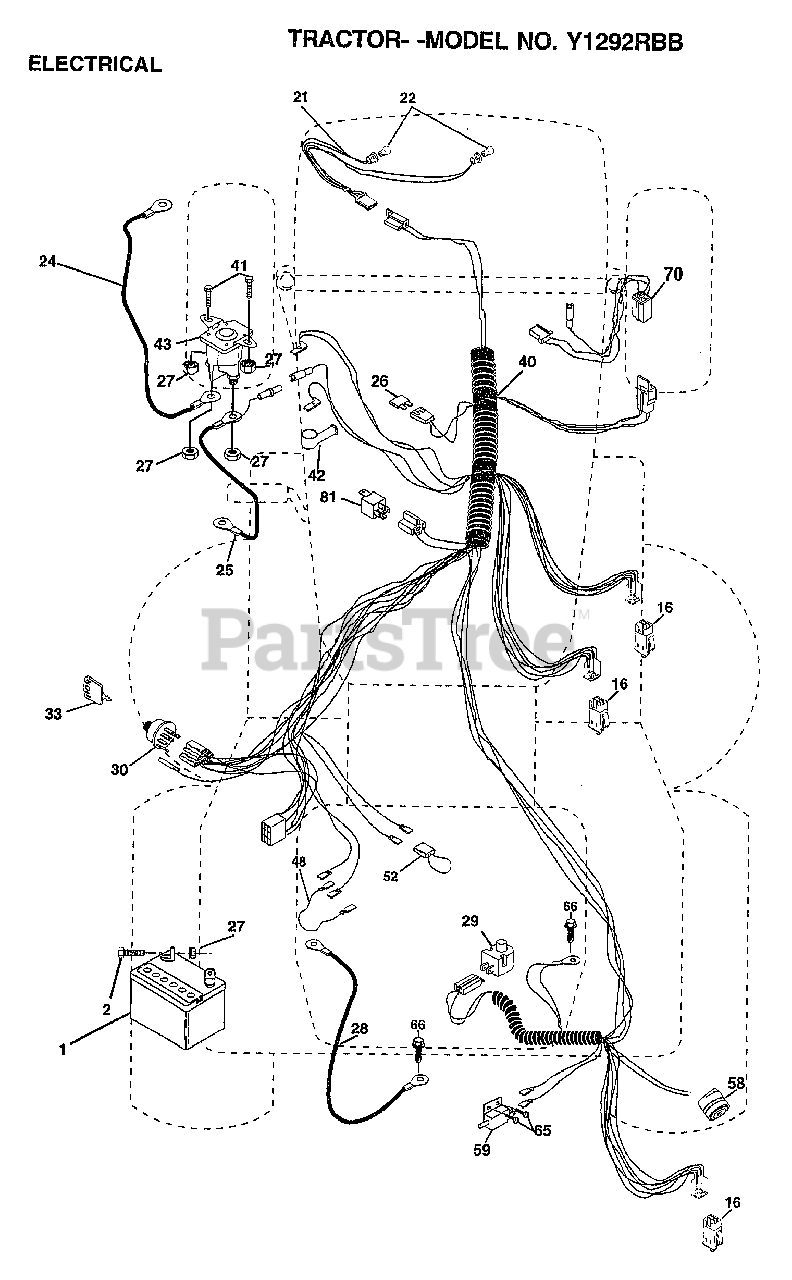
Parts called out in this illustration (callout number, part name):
2	BOLT LT
16	SWITCH INTERLOCK
21	HARNESS.ASM.LIGHT W/4152J
22	HEADLAMP BULB
24	"CABLE T, BATTERY"
25	CABLE.BATTERY.CRD
26	FUSE.15 AMP
27	NUT
28	"CABLE.GRD.6GA/18""BLACK"
29	SWITCH.PLUNGER
30	SWITCH.IGN.
33	KEY MLD GEN DELTA
40	HARNESS IGN CORD
41	BOLT HXHD FIN
48	ADAPTER AMMETER
52	PROTECTION LOOP
58	BUZZER CRD
59	SWITCH.FBI.CRD
65	SCREW
66	SCREW LT
70	HARNESS ENG
81	RELAY ASSY T
